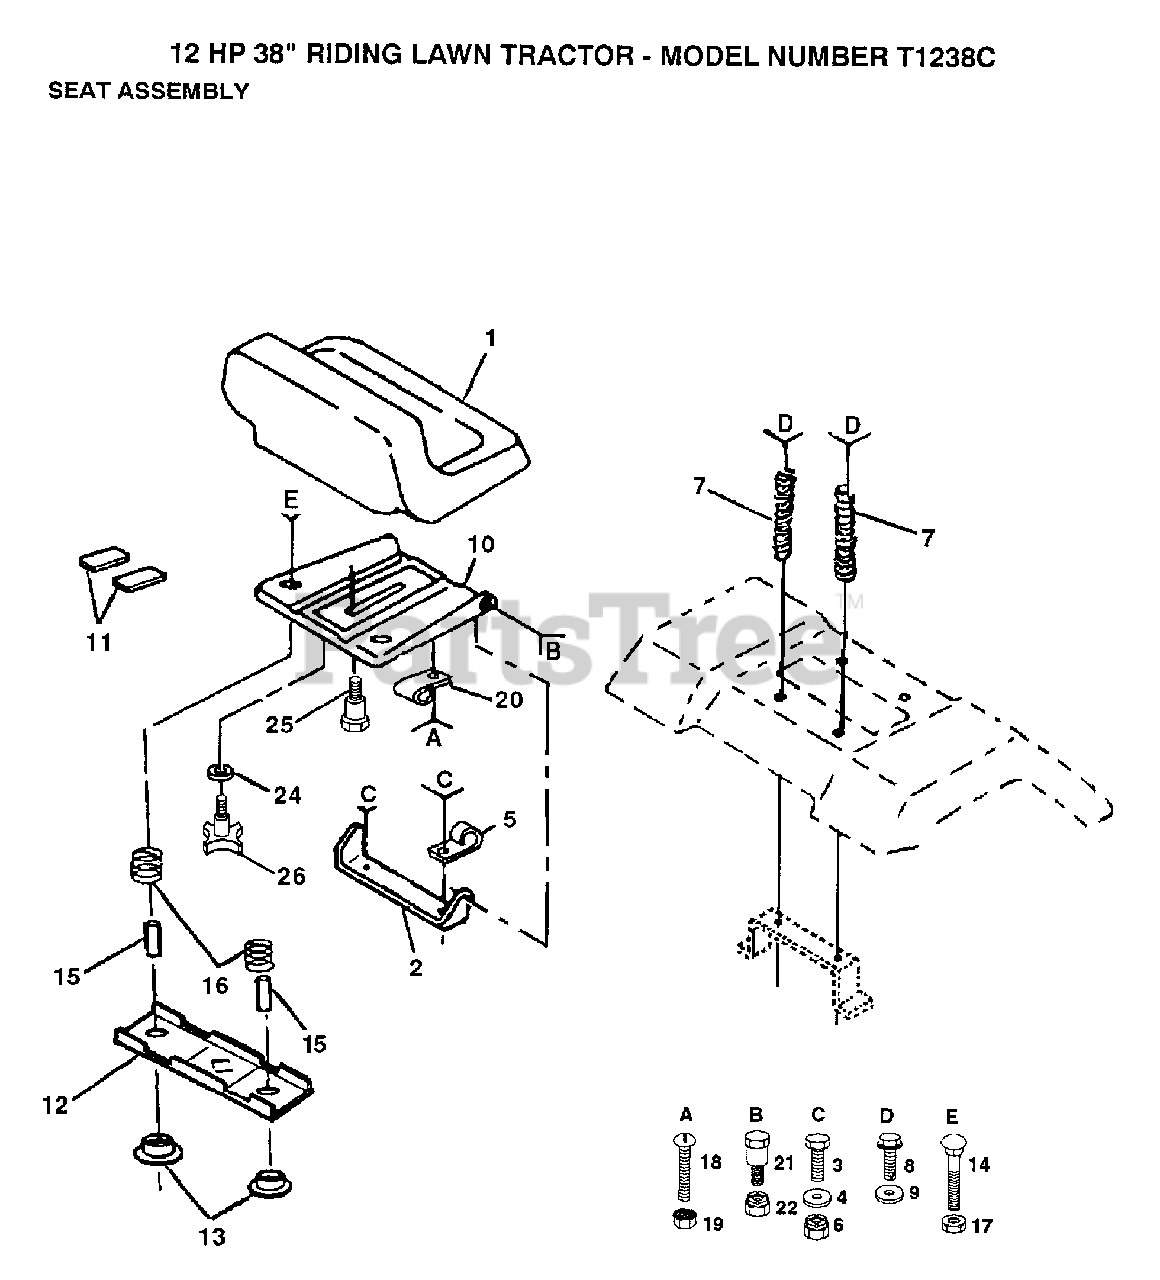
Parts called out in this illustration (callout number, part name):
4	WASHER
5	CLIP T
7	SPRING COMPRESSIO
8	SCREW GTV
9	WASHER
11	STRIP FORM
12	BRKT SWITCH
13	BUSHING
15	SPACER SPLIT
16	SPRING COMPRESSED
19	"NUT,KEPS"
24	WASHER
25	"BOLT,SHOULDER"
26	"KNOB 1/2"" YT"
